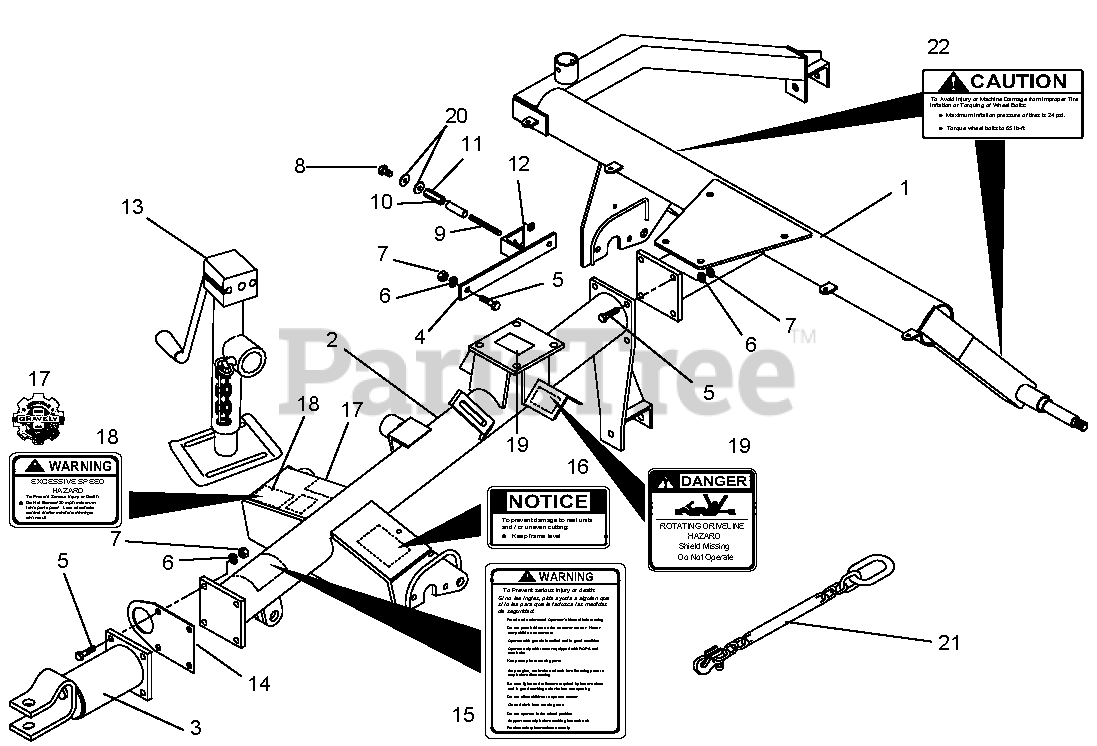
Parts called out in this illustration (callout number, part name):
1	Weldment, Mainframe
2	Tongue Assembly
3	Weldment, Clevis Hitch
4	Weldment, Tongue Brace
5	Cap Screw, Hex Head .50-13 x 1.5
6	Washer, Lock .50
7	Nut, Hex .50 CP
8	Cap Screw, Hex Head .375-16 x .75
9	Stud, Belt Guard
11	Nut, Hex Coupler .375-16
12	Nut, Jam .375-16
13	Jack, Screw 5000-lb.
14	Holder, Hydraulic Hose
15	Decal, Warning
16	Decal, Notice
17	Decal, Gravely Heritage Small
18	Decal, Warning
19	Decal, Danger
20	Washer, Flat .375 SAE
21	Chain, Safety Tow
22	Decal, Caution
